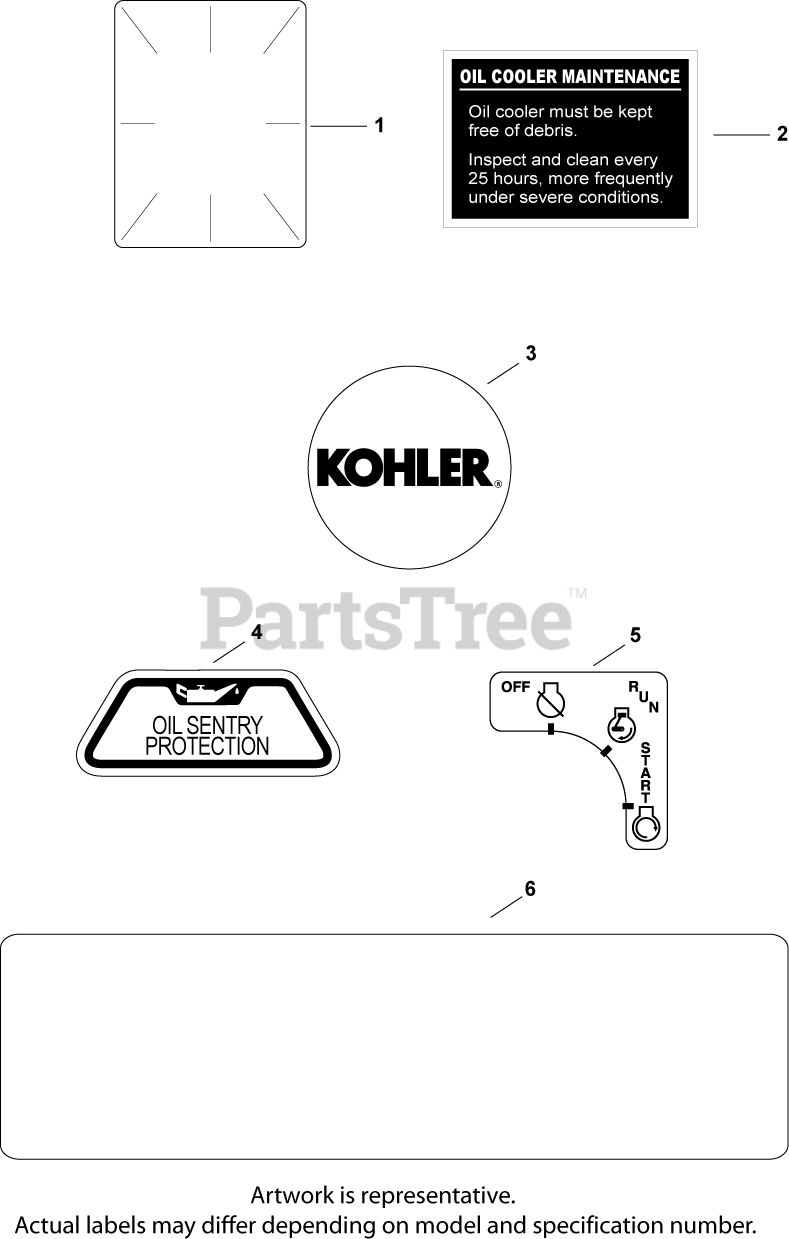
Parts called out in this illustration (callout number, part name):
1	DECAL, CLEAR LAMINATE USE 25 113 70-S
2	DECAL, OIL COOLER - (#DSC)
3	LABEL, (ROUND KOHLER GOLD)-USE 24 113 18
4	DECAL, OIL SENTRY - (#DSC)
5	DECAL, KEY SWITCH
6	DECAL, 25 HP
